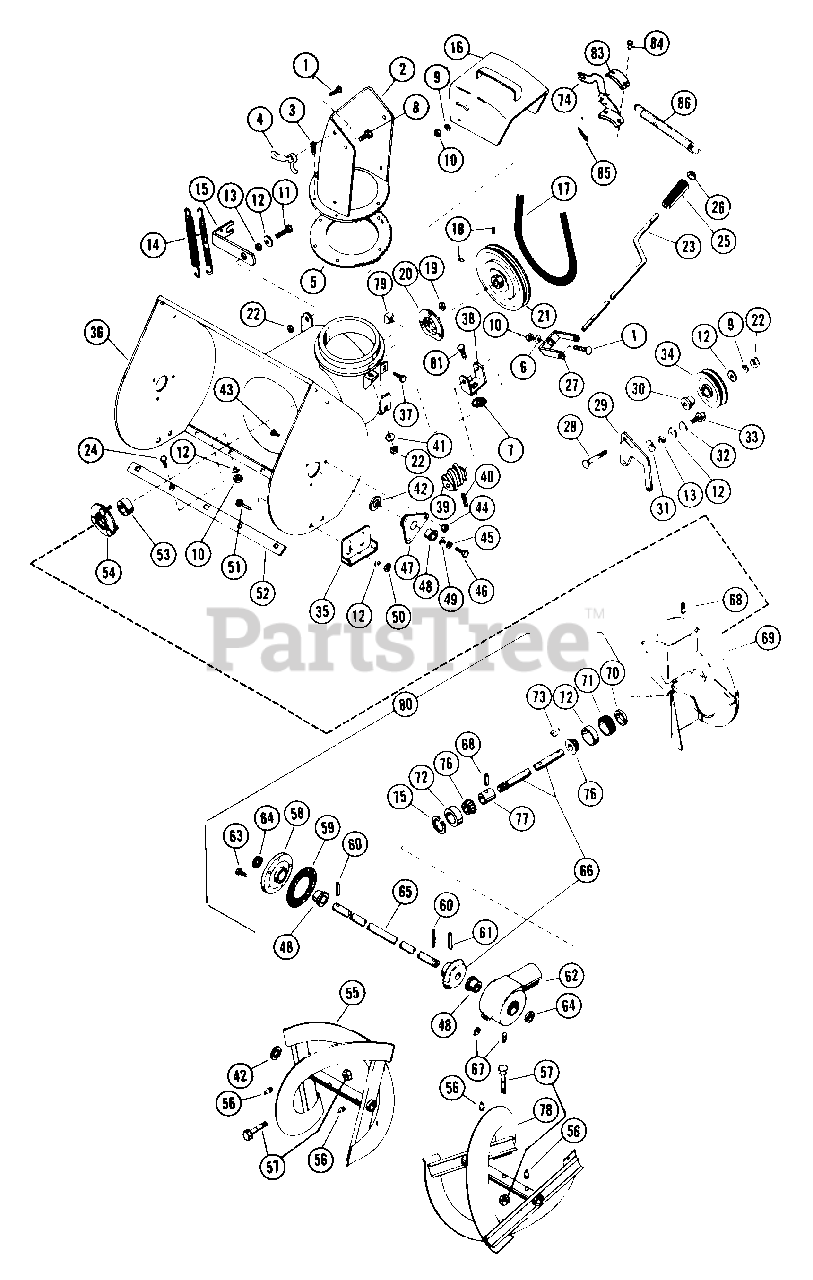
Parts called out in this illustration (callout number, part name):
1	BLT-RDHDSQSHNK .31-18X.50 YZ
2	CHUTE - DISCHARGE
3	SCR-TAP 10-24X.375 HWH PL TR
4	WING NUT, .312-18
5	GEAR - LOWER COLLAR
7	WSHR-LK-EXT .313X.030 PL
8	BLT-HEX .31-18X.50 PL GR2
9	WSHR-LK .312X.097 PL HVY
10	NUT-LK .312-18 GR A PL
11	BLT-HEX .31-18X.75 PL GR2
12	WSHR-FL-STL .38X.875X.083 PL
13	SPACER BUSHING .5 X .32 X .21
14	SG-TENS .125X.437X5.5 WLD 20
15	CLUTCH LEVER
16	DEFLECTOR SERVICE ASSEMBLY
17	V-BELT, 4L-WRAPPED
18	SCR-SET .32-18X.38 SKHCUPNL OH
19	NUT-LK-CTR .250-20 PL
20	BEARING FLANGE
21	PLY-V 8.00 X .75 W/KEY SALEM
22	NUT-HEX .312-18
23	CHUTE CONTROL CRANK
24	BLT-RDHDSQNK .312-18X.62 PL
26	CAP, 3/8 ROD YWZC
27	BRACKET ASSEMBLY
28	BLT-RDHDSQNK .31-18X1.38SHT PL
29	IDLER ARM
30	SPCR, BRG .315X.50X.688X.281
31	WAVE WASHER .531X.781X.125FH
32	WSHR-LK-INT .313X.030 PL
33	BLT-HEX .31-18X.63 PL GR 2
34	IDLER
35	RUNNER
36	BLOWER HOUSING ASSEMBLY
37	BLT-SCRHFWH .38-16X.75 PL
38	WORM CLEVIS
39	WORM GEAR
40	PIN-ROLL .125X.75
41	WSHR-LK .313X.062
42	WSHR-FL-STL 1.010X1.505X.062PL
43	SCR-SLTR-SERNK .25-20X.62 PL
44	NUT-LK-FLG .250-20 PL
45	WSHR-LK .500X.151 HVY PL
46	BLT-HEX .50-13X1.00 PL GR2
47	BEARING SUPPORT
48	BSHG-FLG 1.000X1.12X.62X1.50BR
49	WSHR-FL-STL .511X1.441X.125 PL
50	NUT-LK-CTR .375-16 GR A PL
51	BLT-RDHDSQNK .38-16X.75 SHT PL
52	SCRAPER BLADE
53	BRG-BALL .750X1.750X.50
54	BEARING FLANGE
55	RAKE, RIGHT-20"(1ID X 13.88OD)
55	RAKE, RIGHT-24"(1ID X 13.75OD)
56	SPIN DRIVE ZERK FITTING
57	SHEAR BOLT SERVICE ASSEMBLY
58	GEAR CASE FLANGE
60	PIN-ROLL .188X1.50
61	PIN-ROLL .313X1.38
62	CASE, GEAR - C.I.
63	BLT-SERHFWH .25-20X.75 PL
64	SEAL 1.000X1.312X.150
65	FRONT GEAR SHAFT
66	SHAFT & GEAR SERVICE ASSEMBLY
67	PIPE PLUG
68	PIN-ROLL .250X1.25
70	SEAL .750X1.499X.225
71	ADJUSTMENT PLUG
72	BRG-CUP 1.781X.475
73	KEY-WDRF .188X.75X.313 SAE 9
74	BRAKE ASSEMBLY
75	RG-RTNG INT 1.781 HSG X.062
76	BRG-CONE .750X.61
77	BEARING SPACER
78	RAKE, LEFT-20"(1ID X 13.88 OD)
78	RAKE, LEFT-24"(1ID X 13.75 OD)
79	NUT-RETNR .38-16 TINRMAN
80	GEAR CASE - C.I.
80	GEAR CASE - 24" - CAST IRON
81	BLT-RDHDSQNK .31-18X.75 GR5 PL
82	ARIENS NAME PLATE
83	BRAKE LINING
84	RVT-TBLR .187X.375 OH ST PL
85	PIN-COTR .12X1.0 PL
86	SG-TENS .062X.56X8.0 WLD 11
